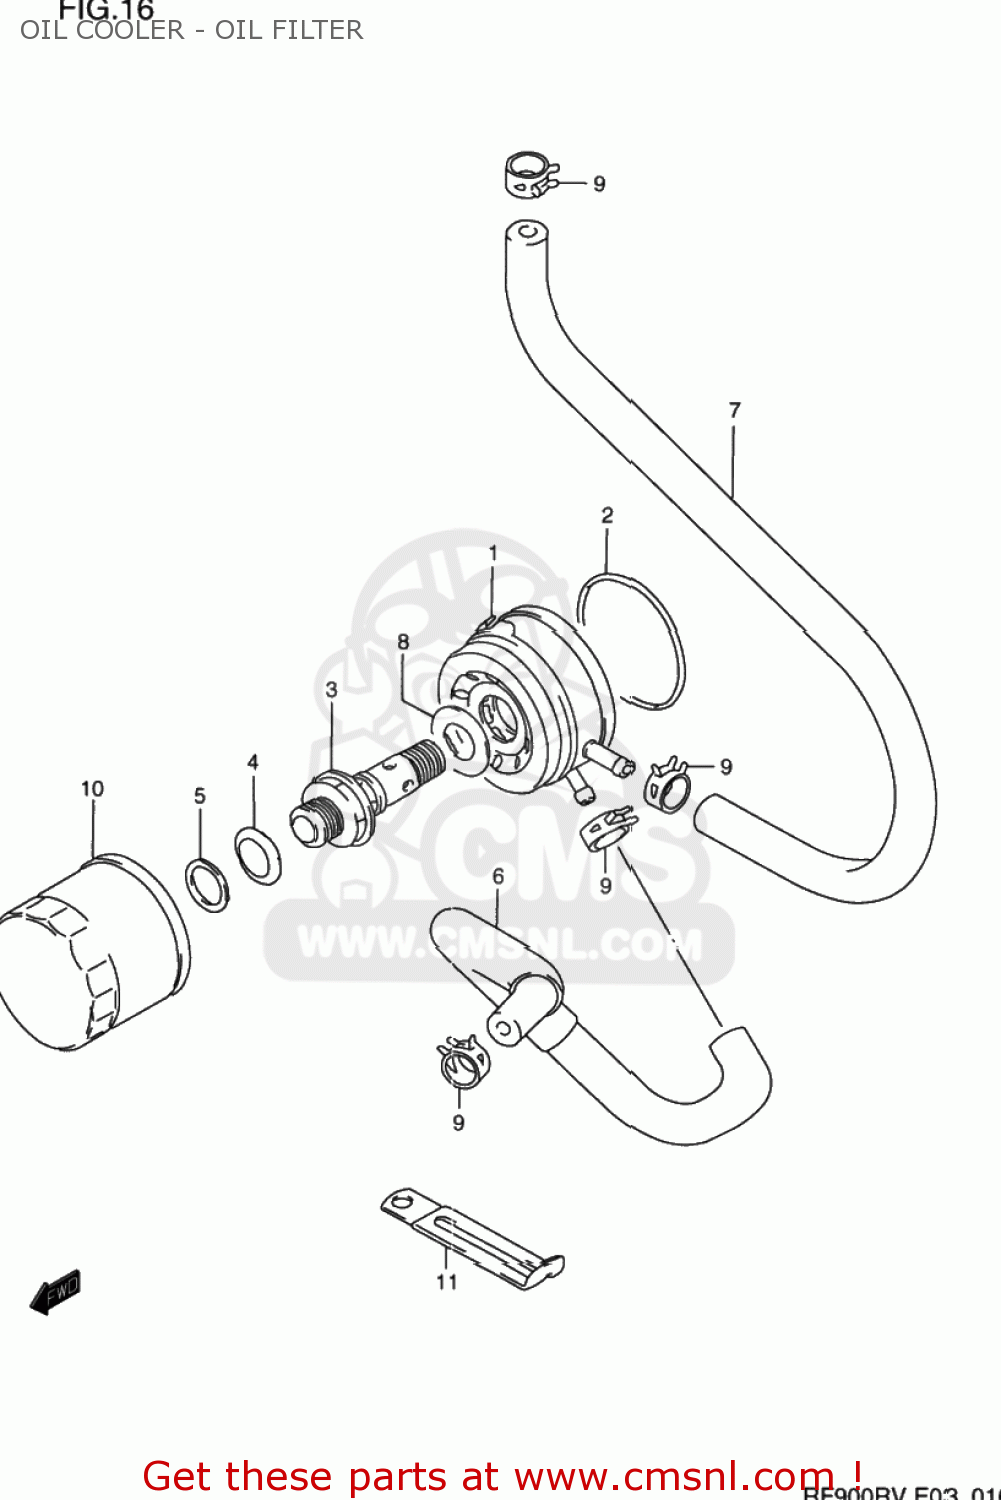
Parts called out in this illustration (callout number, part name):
1	COOLER ASSY,OIL
2	O RING(D:3.1,ID:63.9)
3	BOLT,OIL COOLER UNION
4	WASHER,OIL FILTER WAVE
5	WASHER
6	HOSE,OIL COOLER WATER IN
7	HOSE,OIL COOLER OUTLET
8	SHIM
9	CLIP
10	FILTER ASSEMBLY,ENGINE OIL
11	CLAMP
